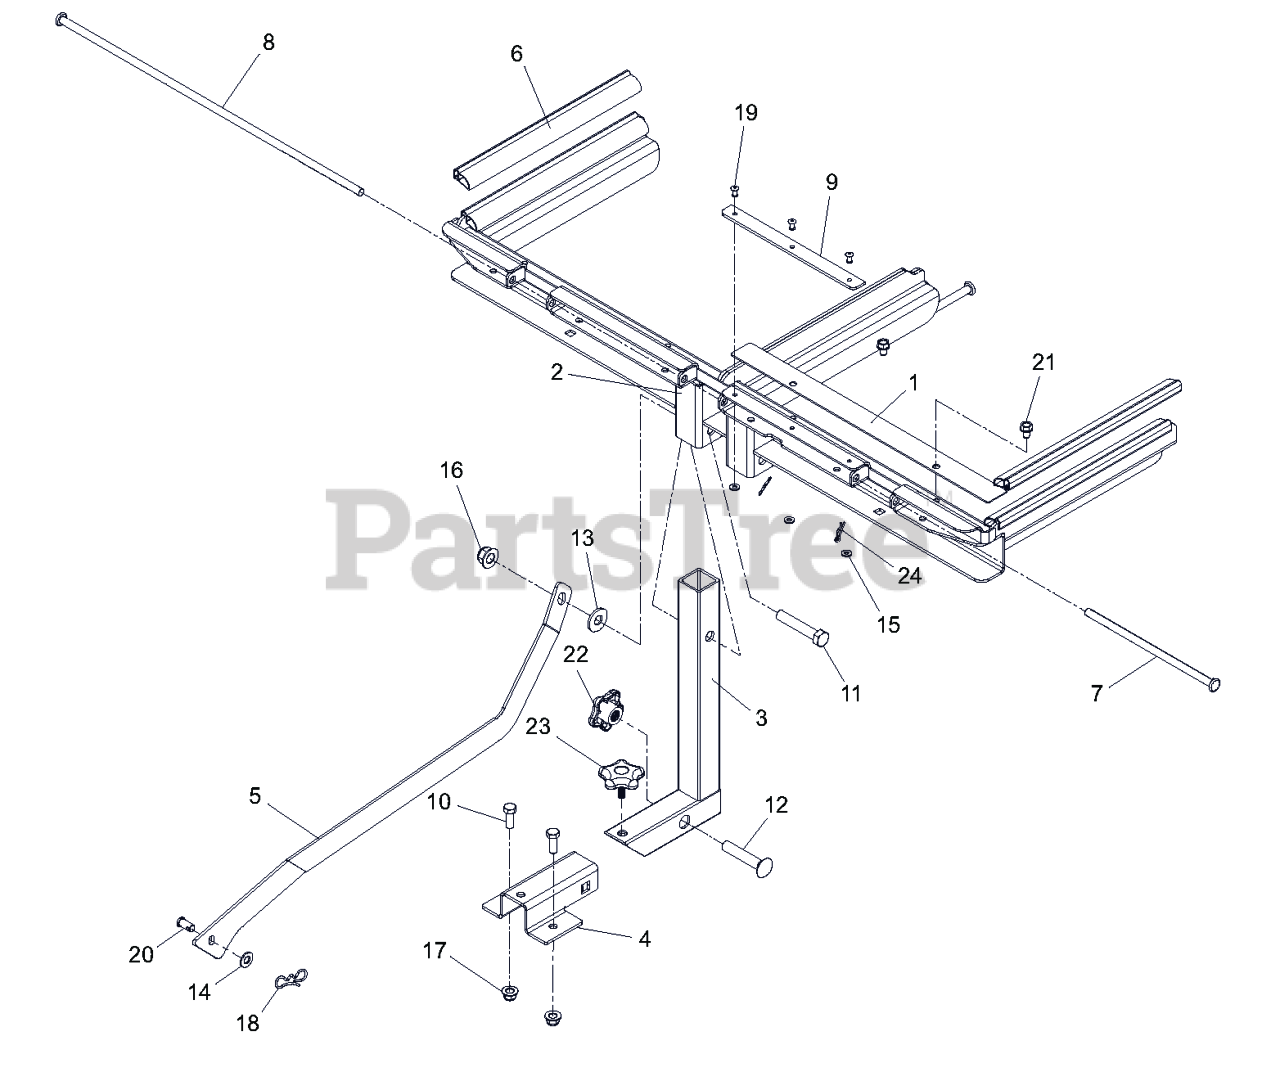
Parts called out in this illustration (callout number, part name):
1	BRKT-BAGGER OVERLAP
2	WLDMT, BAGGER MOUNT POST(2BKT)
3	BRKT, RECEIVER SLEEVE INSERT
4	BRKT, RECEIVER LOWER
6	SEAL, BULK
7	PIN, BAGGER HINGE (L)
8	PIN, BAGGER HINGE (R)
9	SEAL, HINGE
10	@BLT-HEX .38-16X1.00 GR5 YWZC
11	@BLT-HEX .50-13X2.75 GR5 YWZC
12	@BLT-RDHDSQNK .50-13X2.75 G5YZ
13	WSHR-FL-STL .531X1.250X.10 YWZ
14	@WSHR-FL-STL.406X.812X.065 YWZ
15	@WSHR-FL-STL.219X.50X.049 YWZC
16	@NUT-LK-NYL-FLG .50-13 YWZC
17	@NUT-LK-NYL-FLG .38-16 YWZC
18	PIN,BOW TIE LOCKING .091X1.875
19	RVT-POP.187X.527 DOME ST
20	PIN-CLEV .38X.75 YWZC
21	@SCR-TAP .31-18X.50 HWH TR YWZ
22	KNOB, WING
23	KNOB, WING STUDDED
24	PIN-HAIR, ENDRIES #25 YWZC
